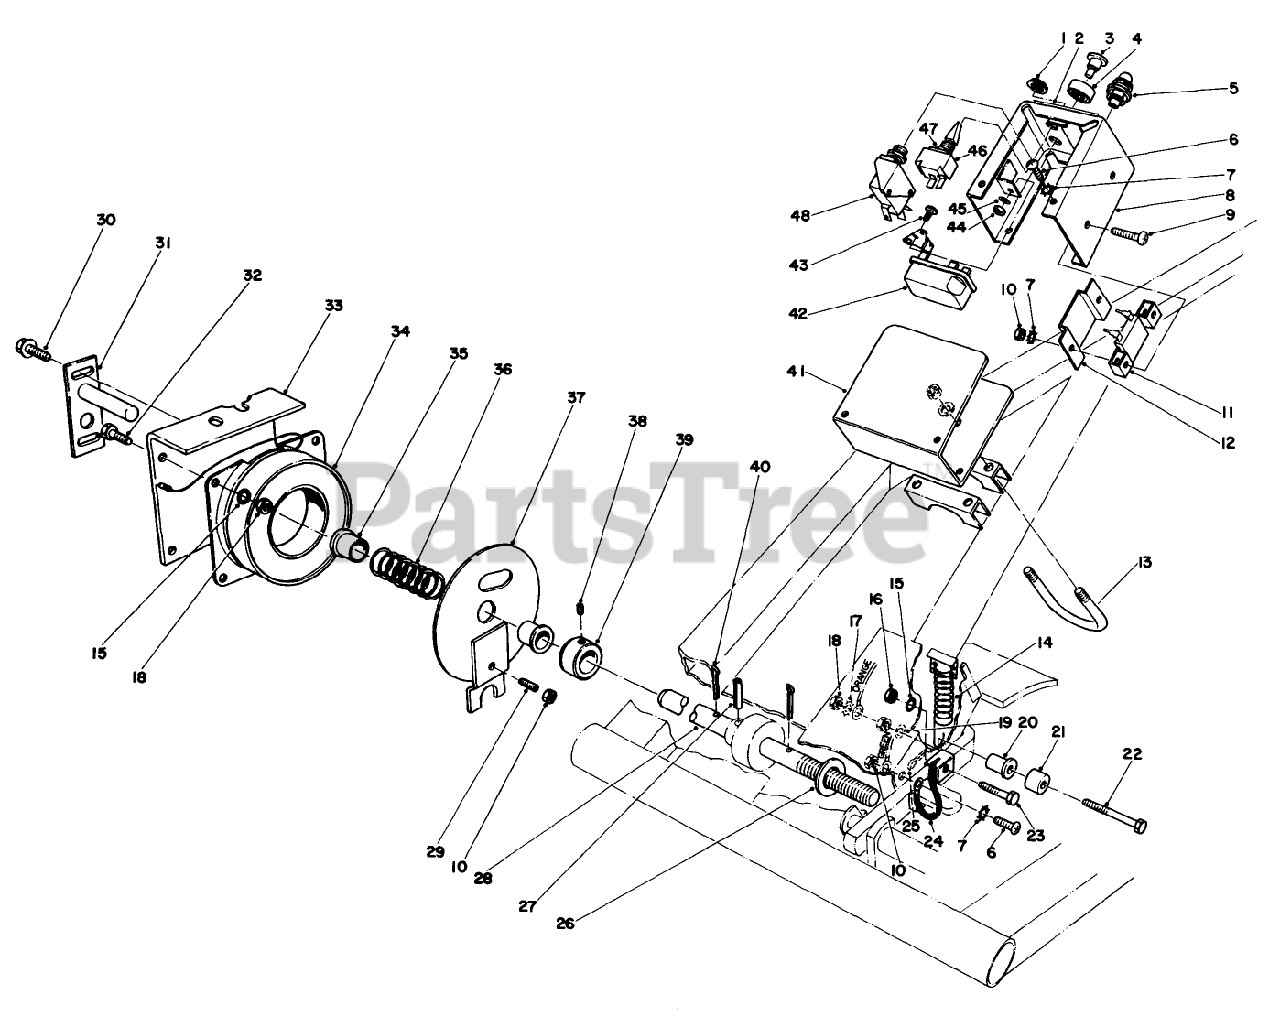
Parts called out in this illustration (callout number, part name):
45	WASHER-LOCK, INTERNAL
46	Light Switch (Incl. Ref. #1 & 47)
47	NUT-LOCK
48	Switch
